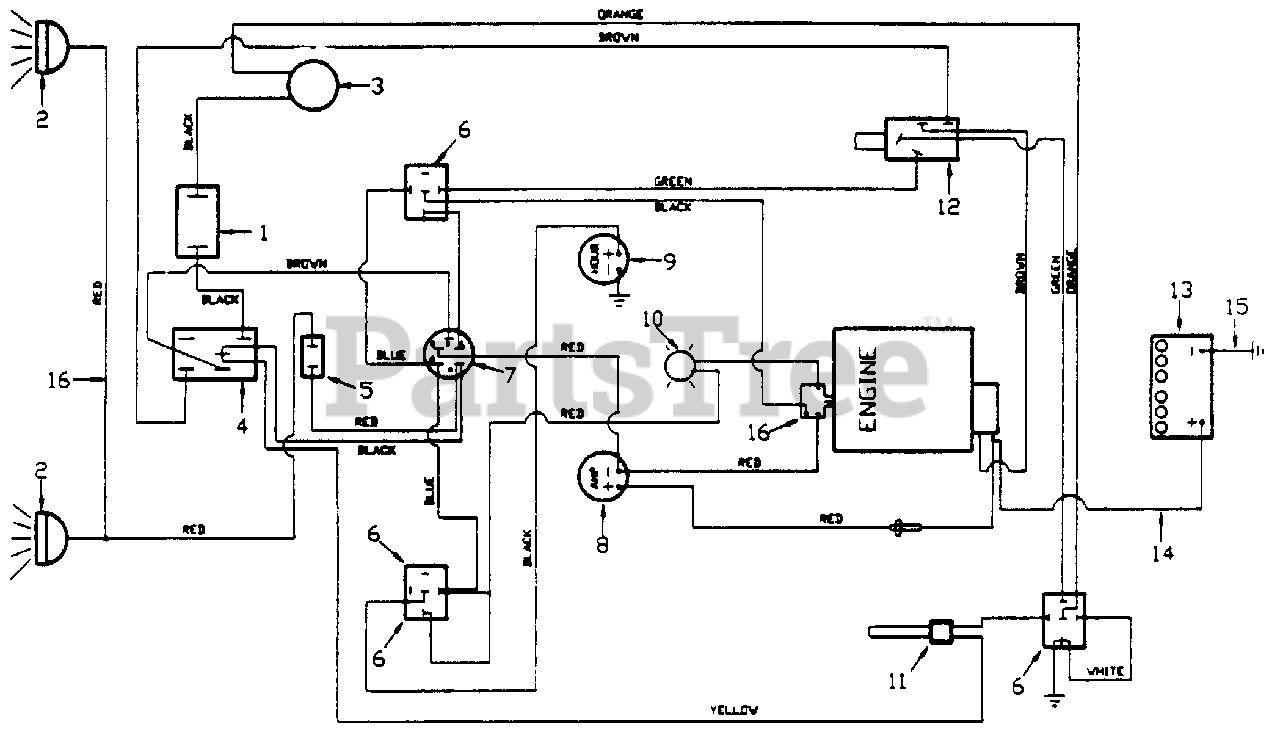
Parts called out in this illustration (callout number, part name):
1	10 Amp Circult Breaker
2	Headlight Assembly
3	Electric Clutch Assembly
4	PT0 Clutch Switch
5	Light Switch
6	Relay
7	Ignition Switch
13	Battery
